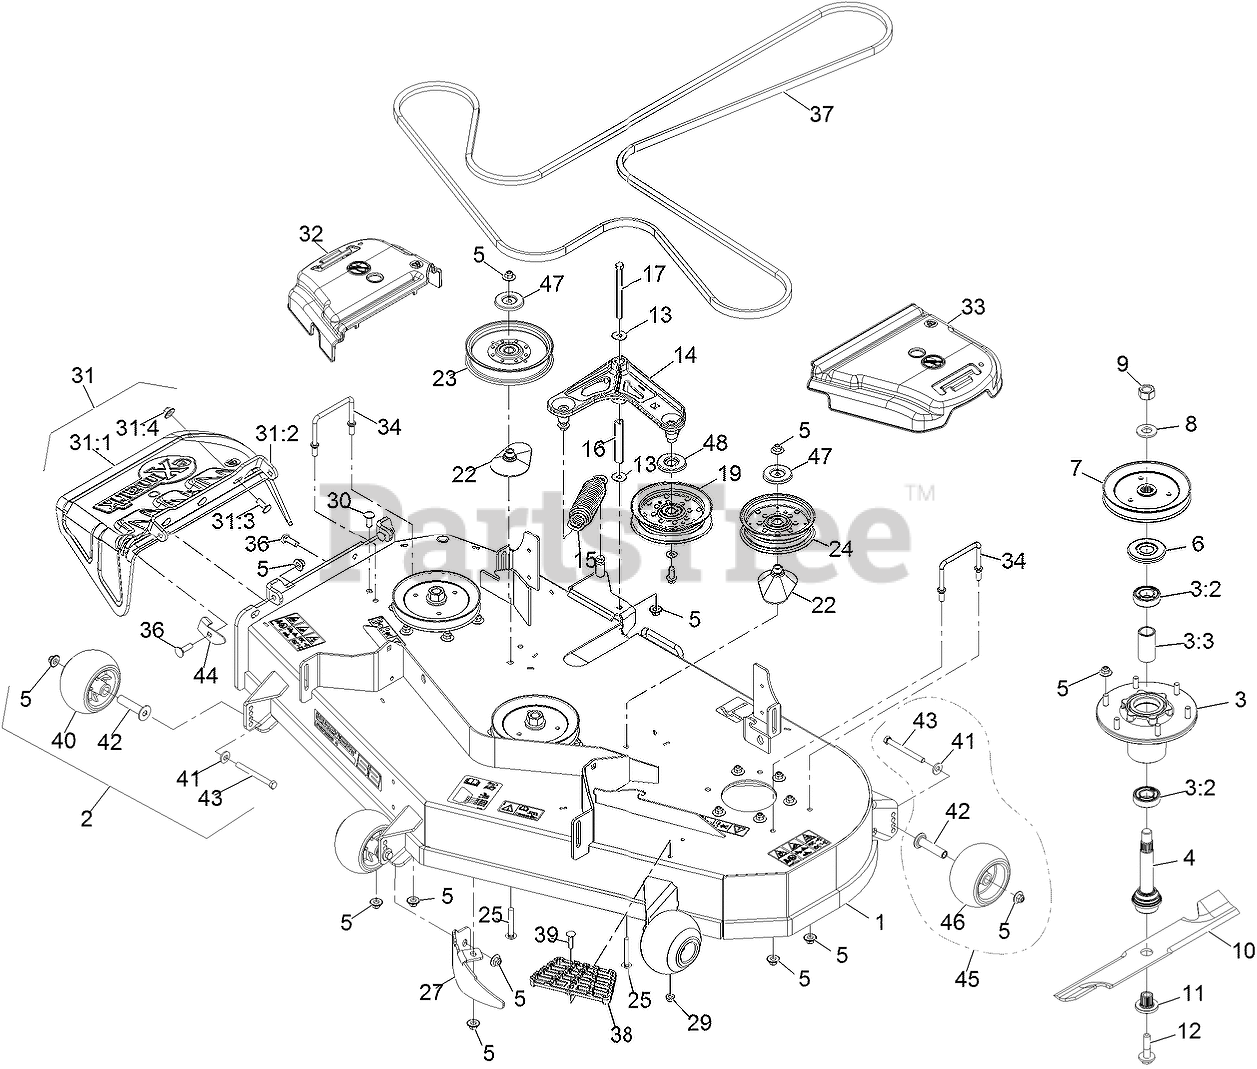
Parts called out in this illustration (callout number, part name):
1	ASM-DECK W/DECALS 524
2	KIT, ANTI-SCALP ROLLER
3	ASM-CUTTER HSG WITH BEARINGS
3:2	BEARING-BALL
3:3	SPACER-BEARING
4	ASM-SPINDLE AND SEAL
5	Nut-Nyloc 3/8-16 Flg
6	GUARD,BEARING TOP .989
7	SHEAVE,BLADE DRIVE 6.50
9	NUT-HEX
11	BUSHING,SPLINED
12	SCREW,SEMS 1/2-20 X 2.19
14	IDLER ARM ASM
15	SPRING-EXTENSION
16	BUSHING
17	SCREW-HH
19	IDLER-PULLEY, FLAT
22	SPACER-PULLEY
23	IDLER-PULLEY, FLAT 6.00X1.00
24	IDLER-PULLEY, FLAT 5.00X1
25	SCREW-CARR
27	BAFFLE-DOGLEG, LZ-VT52
29	NUT-HF, NI
30	SCREW-CARR
31	ASM,DISCHARGE CHUTE
31:1	CHUTE,DISCHARGE
31:2	BRACKET,DISCHARGE CHUTE
31:3	SCREW-CARR
31:4	Nut-Nyloc 3/8-16 Flg
32	COVER-BELT, RH
33	COVER-BELT, LH
34	WIREFORM-COVER
36	BOLT-CARR
38	STEP-DECK
39	Bolt-Carriage 5/16-18 X 1 1/4
40	ROLLER-SCALP, ANTI
41	WASHER-BELLEVILLE
42	AXLE, ROLLER
43	SCREW-HH 3/8-16 X 3 3/4 GR 8
44	STOP-DISCHARGE CHUTE
45	KIT-ANTISCALP ROLLER
46	ROLLER-SCALP, ANTI
47	SHIELD-DUST
48	SHIELD-GUARD, DUST
